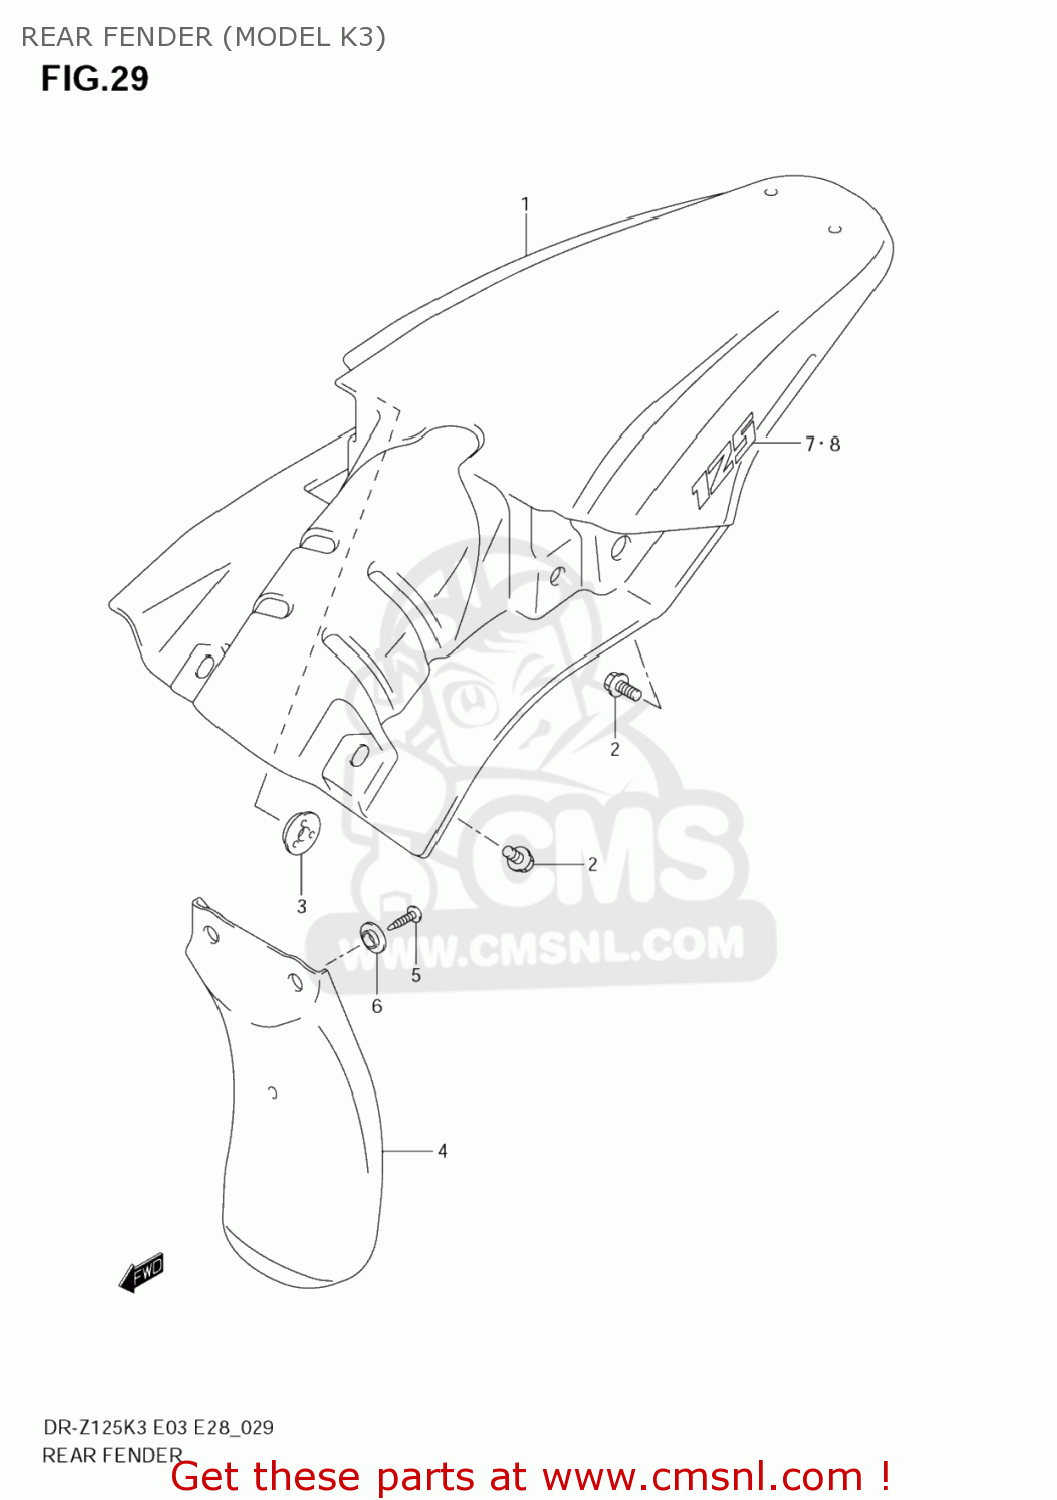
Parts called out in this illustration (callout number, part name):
1	FENDER,RR
2	BOLT
3	WASHER
4	MUDGUARD,RR FENDER FR
5	SCREW
6	WASHER
7	EMBLEM,R
8	EMBLEM,L
